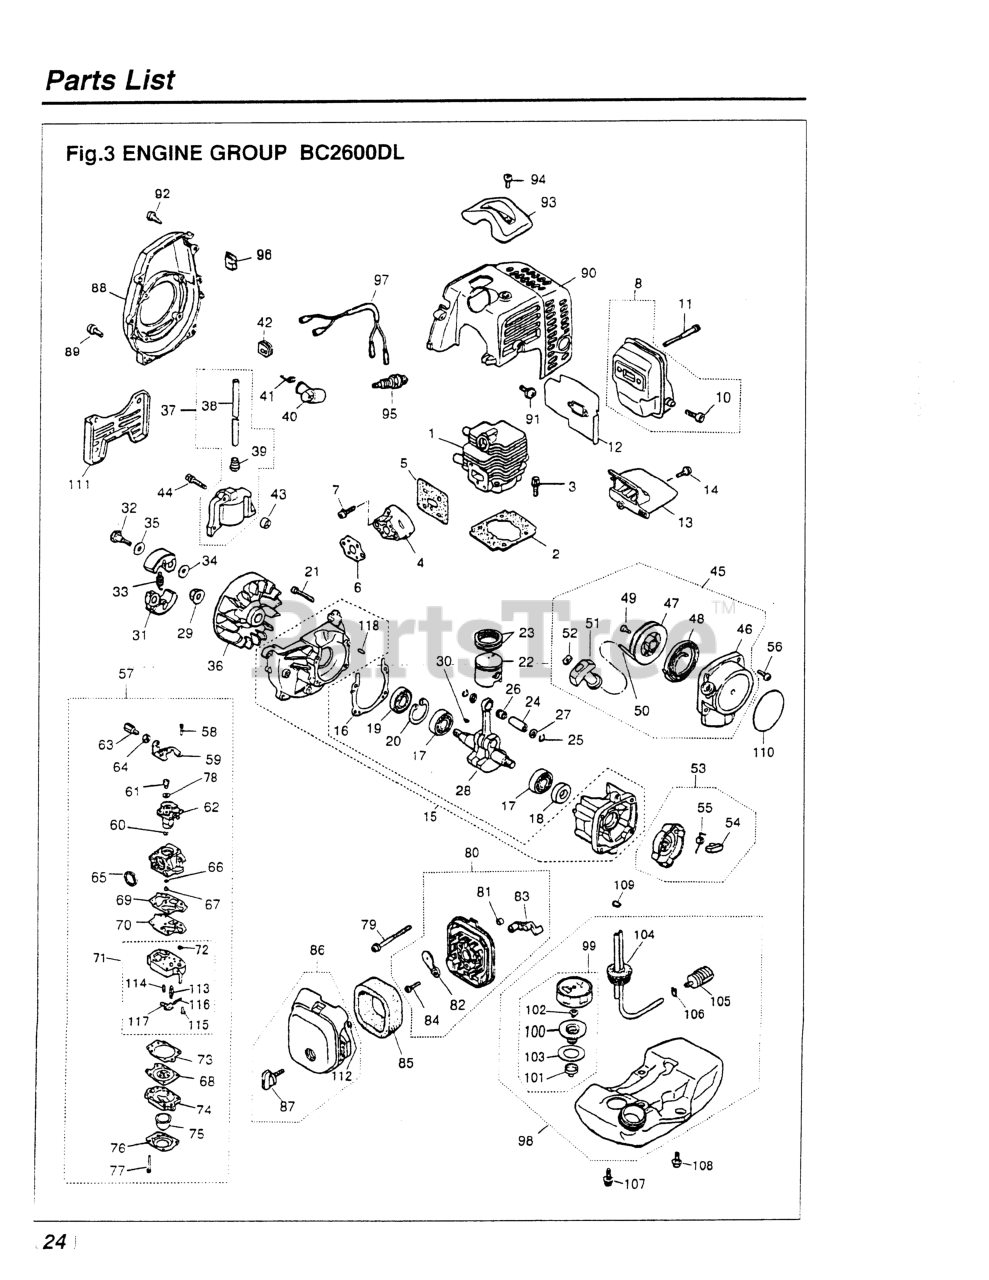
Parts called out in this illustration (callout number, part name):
1	CYLINDER
3	BOLT, M5 X 22
4	INSULATOR (USE -13163)
5	GASKET (RPLS -13120)
6	GASKET (REPLACES -13130)
7	SCREW, M5X20 (RPLS.1400-75510)
8	MUFFLER ASSY (RPLS 5501- )
10	ARRESTER (RPLS 5850-15140)
11	BOLT, M5 x 50
12	GASKET, MUFFLER (RPLS -15111)
14	SCREW, M4 X 16
15	CRANKCASE
16	GASKET (RPLS -21140)
17	BEARING
18	SEAL, OIL (RPLS 1100-21210)
19	SEAL, OIL (RPLS 1140-21220)
20	RING, SNAP, M28 x 1.2
21	BOLT, M5 X 30
22	PISTON
23	RING, PISTON
24	PIN, PISTON
25	RING, SNAP (RPLS 1101-41320)
27	WASHER
28	CRANKSHAFT (RPLS 1850-42000)
30	KEY
31	SHOE (RPLS 1100-51114)
32	BOLT
33	SPRING, CLUTCH (RPLS-51220)
34	WASHER, FLAT (USE 182303)
36	ROTOR
37	COIL ASSY (RPLS 5500-71200)
38	CORD
39	CAP
41	SPRING
42	GROMMET
43	SPACER (RPLS -71260)
44	BOLT
45	RECOIL ASSEMBLY
46	CASE
47	REEL
48	SPRING, SPIRAL
49	SCREW (RPLS -75150)
51	KNOB
52	PLATE, STOPPER
53	PULLEY ASSY (RPLS -75210)
54	RATCHET (RPLS 1850-75220)
55	SPRING, RETURN
56	SCREW, M4 X 16
57	CARBURETOR (WYJ-117)
58	SCREW
60	RING
61	SWIVEL
62	VALVE ASSY
63	SCREW, CABLE ADJUSTER
64	NUT, CABLE ADJUSTER
65	RING, PACKING
66	RING, O
67	JET
68	DIAPHRAGM (USE 4810-81260)
69	GASKET, PUMP
70	DIAPHRAGM
71	BODY, PUMP
73	GASKET, DIAPHRAGM
74	BODY, PURGE
75	PUMP, PRIMING
76	COVER, PUMP
77	SCREW
78	WASHER
79	SCREW, M5 X 55
80	BODY-A (RPLS -82101)
81	SLEEVE
82	PLATE, CHOKE (RPLS-82130)
83	LEVER, CHOKE
84	SCREW (REPLACES 50030272)
85	ELEMENT
87	KNOB (RPLS -82220)
88	COVER, FAN (RPLS-31110)
89	SCREW, M5X20 (RPLS.1400-75510)
90	COVER, ENGINE (RPLS -32111)
91	SCREW, M5 x 12
92	SCREW, HOUSING
93	GUARD, PLUG
94	SCREW,M5 X 14 (RPLS 1400-15510
97	CORD COMP (RPLS -73200)
101	HOLDER, CAP
102	VALVE (NLA WHEN OUT)
103	PACKING
104	PIPE COMPLETE
105	FILTER (RPLS 1850-85300)
106	CLIP (REPLACES 2841-31280)
107	SCREW
108	SCREW W/ WASHER
109	CLIP
110	LABEL, RECOIL (RPLS -91120)
111	STAND
112	RING
113	VALVE, INLET
114	SPRING, METERING LEVER
115	SCREW, METERING LEVER PIN
116	PIN, METERING LEVER
117	LEVER
118	PIN
